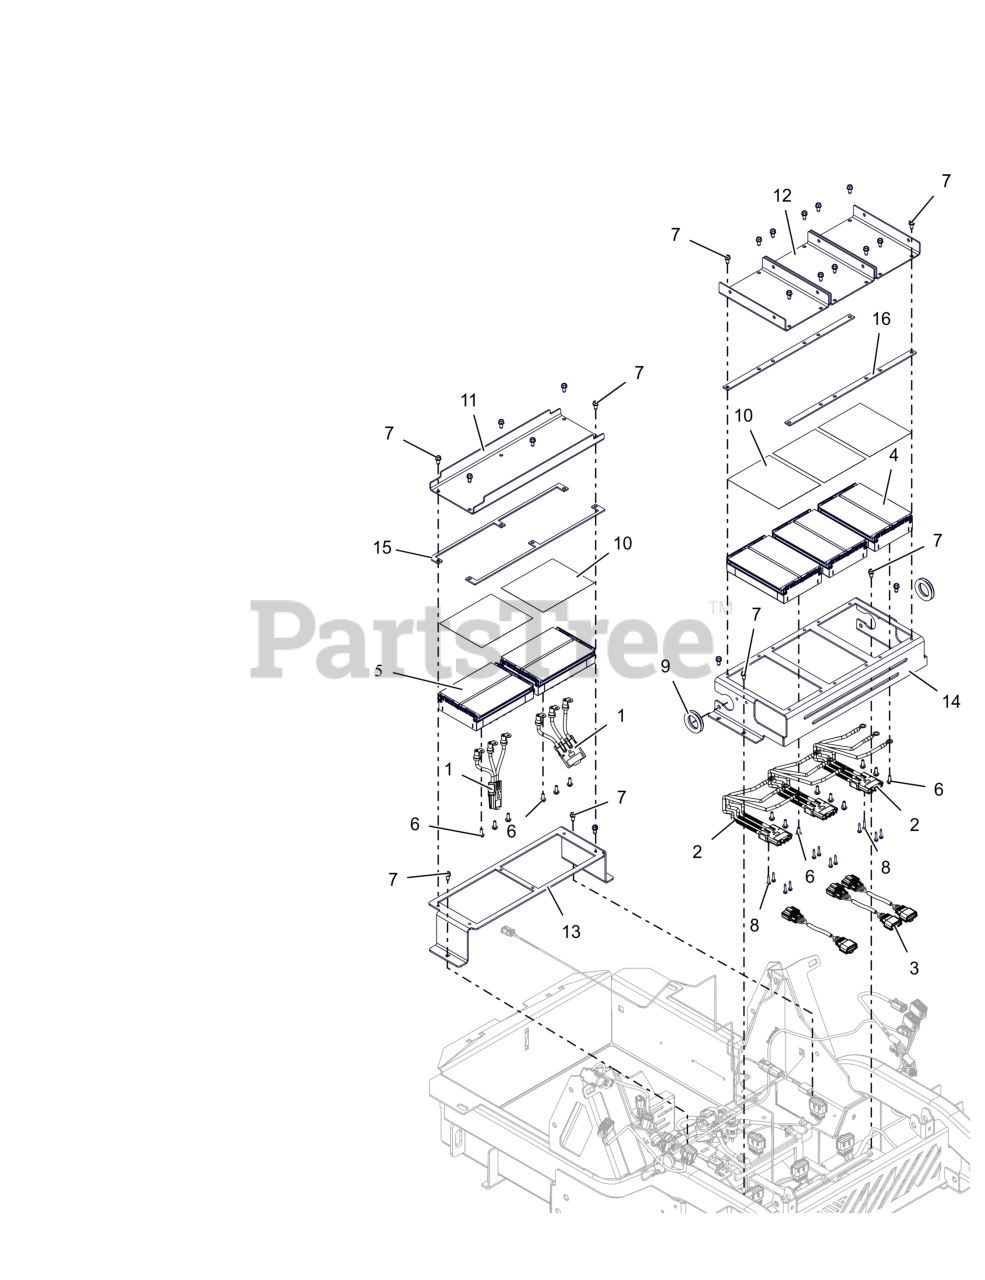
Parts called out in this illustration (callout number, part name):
1	HARNESS, DRIVE CONTROLLER
2	HARNESS, DECK CONTROLLER
3	HARNESS, DECK CNTRL JUMPER
4	KIT, MY23 48 DECK CONTROLLER
5	KIT,MY23 PTEV DRVIE CONTROLLER
6	BLT,HEX M5-.8X16 EP30 G8.8 ZCC
7	SCR-TAP .25-20X.50 HWH ZCC
8	SCR-TAP #6-32X.75 HWH ZCC
9	GROMMET 1.25ID X 1.5OD
10	PAD, THERMAL
11	PLATE, HEAT SINK-REAR
12	PLATE, HEAT SINK-FRONT
13	MOUNT, CNTRL -DRIVE (BLACK)
14	MOUNT, CONTROLLER PLATE-FRONT (BLACK)
15	SPCR, HEAT SINK (BLACK)
16	SPCR, HEAT SINK - FRONT (BLACK)
